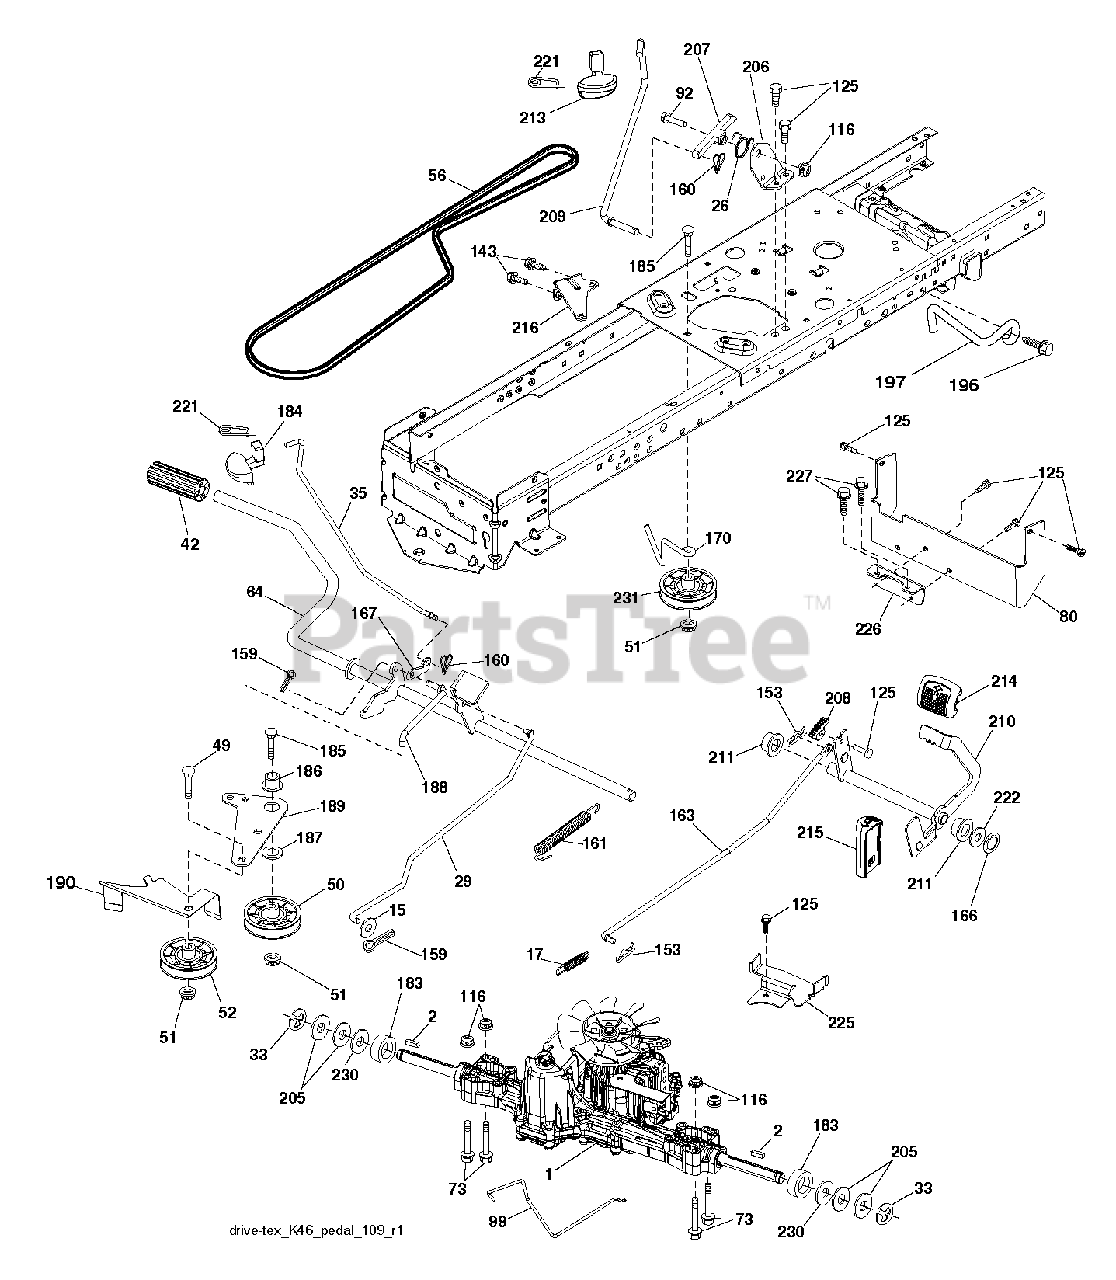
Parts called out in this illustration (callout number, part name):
2	SQUARE KEY
15	WASHER
17	SPRING.BRAKE.K46.GREEN
26	SPRING.RETURN.CRUISE
29	ROD.BRAKE.K46
35	ROD .BRAKE. PARKING. GT. HUSQ.
42	PEDAL COVER T
50	IDLER.FLAT.910.OFFSET
51	NUT LOCK FLG 3/8-16 UNC
52	IDLER.V-GROOVE.910.OFFSET
56	V-BELT.MOWER.92.40.42/K46
64	SHAFT.ASM.PEDAL.BRK.CNTR
73	BOLT
80	STRAP.TORQUE.K46.K57R.TT
92	BOLT
99	ROD.SPRING.BYPASS.K46.LT.Z
116	NUT LOCK HEX FLANGE 5/16-18
125	SCREW
143	SCREW LT
153	RETAINER M
159	COTTER PIN
160	RETAINER CLIP
161	SPRING, RETURN LT
163	ROD.CONTROL.K57R.K46
166	NUT.PUSH.625
167	LATCH.BRAKE.SPRING
170	KEEPER.CENTER SPAN.1.688
183	SPACER AXLE
184	RB HANDLE.PARKG.BRK.HUS/PRED
186	SPACER.RETAINER
187	WASHER 12/32X2X10GA
188	RP LINK.CLUTCH.GROUND.DRIVE
189	BELLCRANK.GROUND.DRIVE.TEX.
190	KEEPER.BELLCRANK.DRIVE
196	SCREW 3/8-16X1
197	LINK.CLUTCH.ANIT-ROTAT
206	BRACKET.MOUNT.CRUISE.LATCH
207	LATCH.CONTROL.CRUISE
208	GEAR.SECTOR.CONTROL.CR
209	ROD.CONTROL.CRUISE.GT.
210	ROCKER.ASM.PEDAL.CONTR
211	BEARING.NYLON
213	KNOB.CONTROL.CRUSIE.HU
214	PEDAL.FORWARD.PAD.TEX
215	PEDAL.REVERSE.TEX.GT.4
216	BRACKET.PULLEY.IDLER.W/TEX
221	RETAINER.SPRING.CLIP.H
222	WASHER 21/32 X 1-1/4 X 10 GA.
225	KEEPER.BELT.TRANSAXLE.K46
226	BRACKET.MOUNT.TORQUE.K46.TLT
227	SCREW
230	WASHER.HARDENED
231	IDLER.V-GROOVE.1.688.OFFSET
